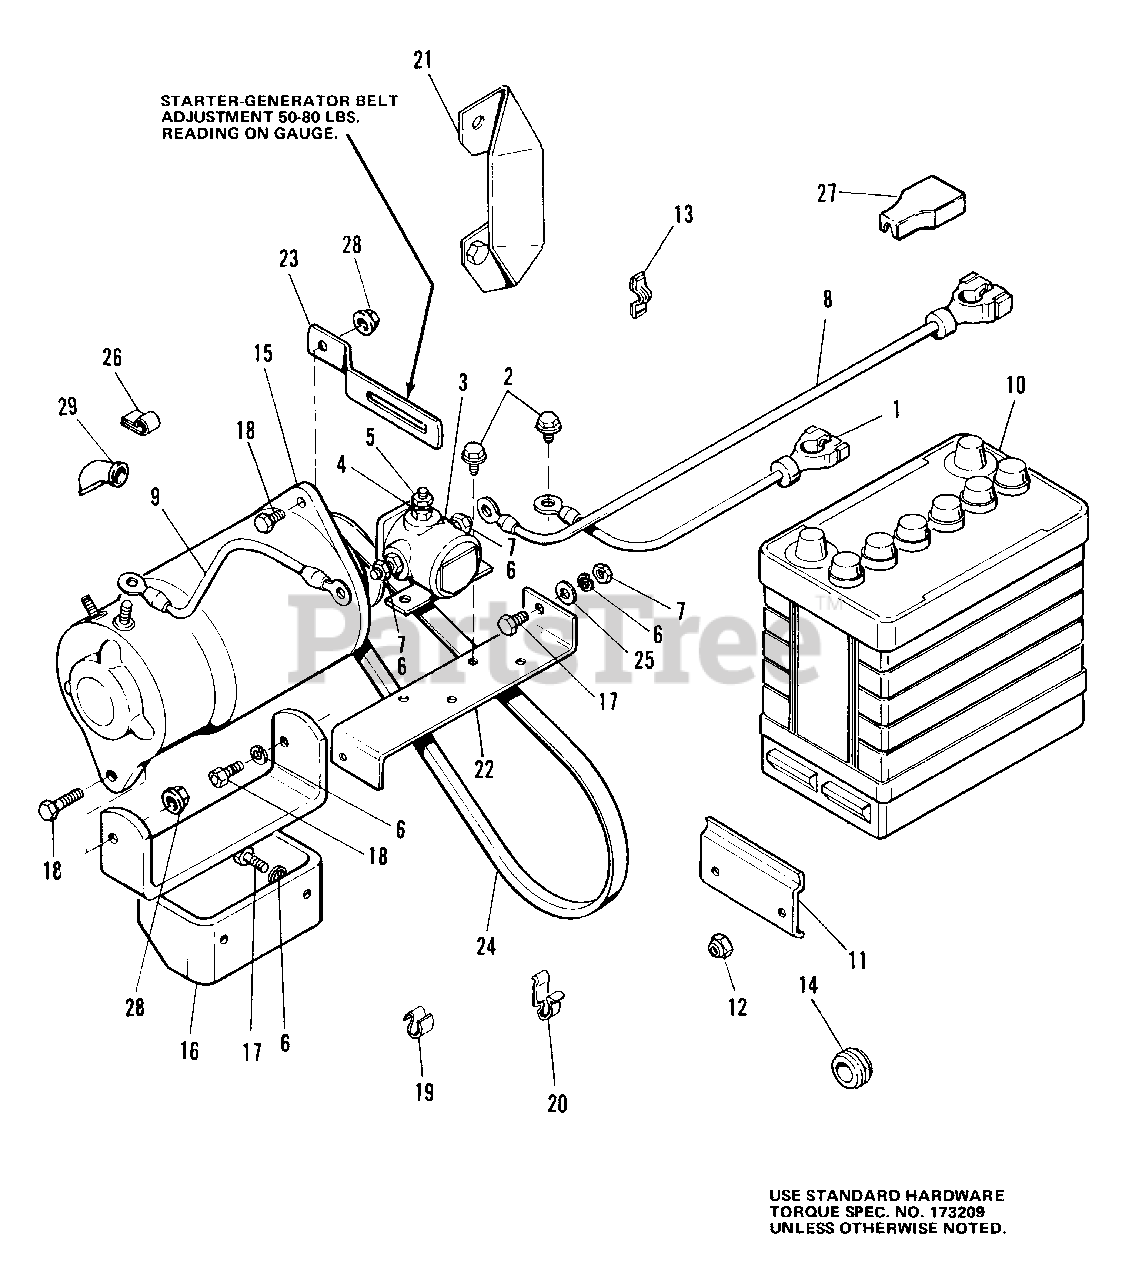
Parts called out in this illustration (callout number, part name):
1	CABLE, Battery to Ground
2	SCREW, Taptite, 1/4-20 x 1/2
4	LOCKWASHER, No 10
5	NUT, Hex, No. 10-32
6	LOCKWASHER, 5/16
7	NUT, Hex, 5/16-18
8	CABLE, Battery to Solenoid
9	CABLE, Solenoid to Start
12	NUT, Elastic, 5/16-18
13	CLIP, Wire
15	MOTOR, Generator
16	SUPPORT ASSEMBLY
17	CAPSCREW, Hex Hd., 5/16-18 x 3/4
18	CAPSCREW, Hex Hd . Flange, Whizlock, 5-/16-18 x 1-1/4
19	CLIP, Tinnerman
20	CLIP, Tinnerman
21	PULLEY GUARD ASSEMBLY
23	ARM, Adjusting
24	V-BELT, 39.12"
25	WASHER, 5/16
26	CLIP, Cable
27	PROTECTOR, Terminal
28	NUT, Flange, Whizlock, 5/16-18
29	COVER, Terminal
